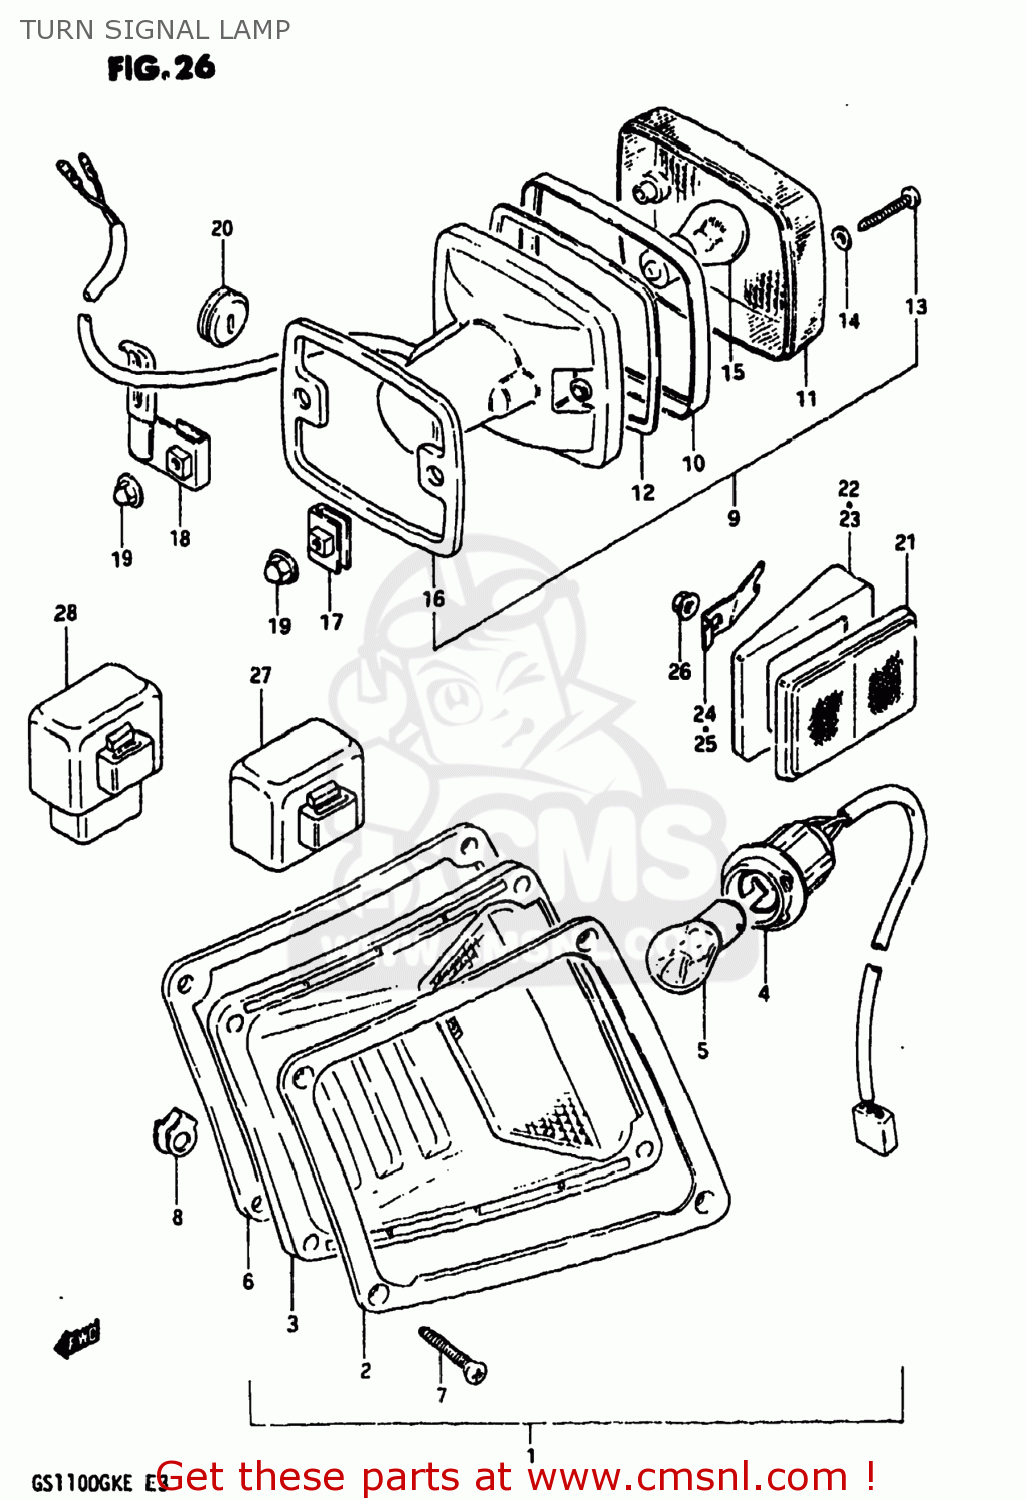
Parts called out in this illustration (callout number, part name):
1	LAMP ASSEMBLY,FRONT TURN SIGNAL
2	RIM,FRONT TURN SIGNAL LAMP
3	COVER,COWLING
4	SOCKET & CORD
5	BULB(12V23W)
6	GASKET,TURN SIGNAL LAMP
7	SCREW,TURN SIGNAL LAMP
8	PLATE
9	LAMP ASSEMBLY,REAR TURN SIGNAL
10	RIM
11	LENS,TURN SIGNAL
12	GASKET (NAS)
13	SCREW,TURN SIGNAL LAMP
14	GASKET (NAS)
15	BULB(12V23W,STANLEY,A4577A)
16	GASKET
17	PLATE,RR TURN SIGNAL
18	CUSHION
19	NUT
20	GROMMET,TURN SIGNAL LAMP
21	REFLEX REFLECTOR,RR
22	SPACER
23	SPACER
24	WASHER,RIGHT
25	WASHER,REFLECTOR LH
26	NUT
27	RELAY ASSY,TURNSIGNAL
28	UNIT,TURN SIGNAL CONTROL
